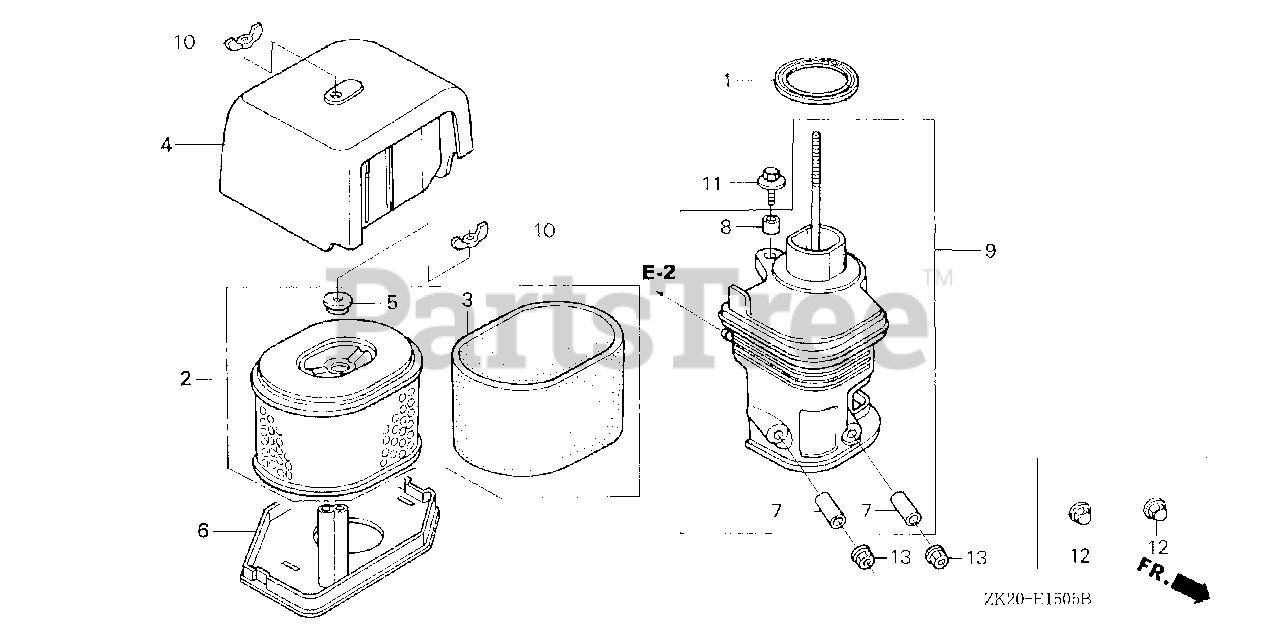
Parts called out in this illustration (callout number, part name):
1	GASKET, ELBOW
2	ELEMENT, AIR CLEANER
3	FILTER (OUTER)
4	COVER, AIR CLEANER (100DB)
5	GROMMET, AIR CLEANER
6	NOSE, MUFFLER
7	COLLAR, AIR CLEANER
8	COLLAR B, AIR CLEANER
9	ELBOW, AIR CLEANER
10	WINGNUT, TOOL BOX SETTING
11	BOLT-WASHER (6X20)
13	NUT, FLANGE (6MM)
